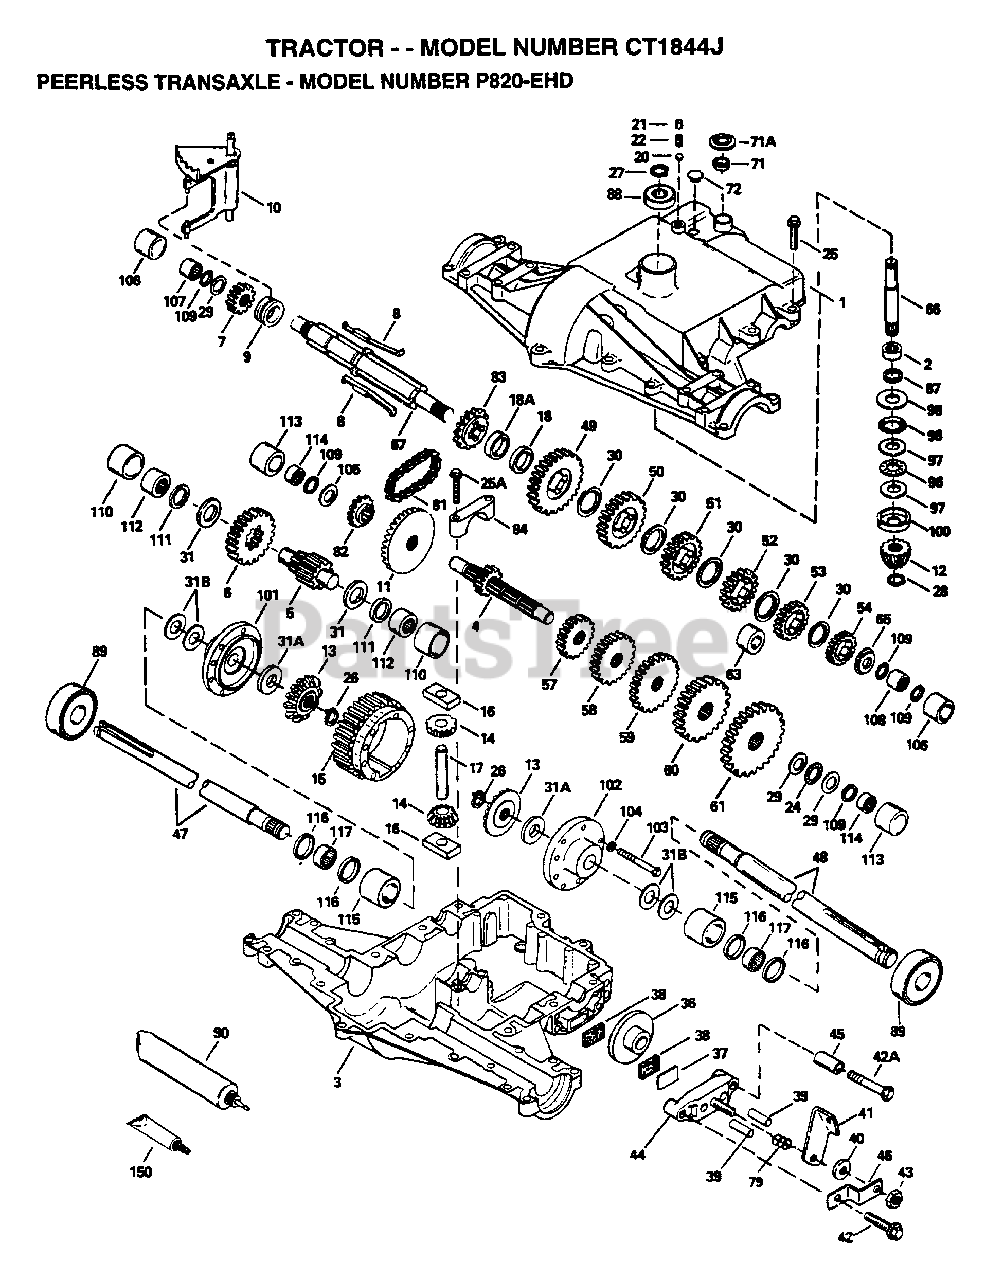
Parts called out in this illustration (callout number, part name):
1	COVER TRANSAXLE
2	BEARING NEEDLE
3	CASE TRANSAXLE
4	SHAFT COUNTER
5	SHAFT, OUTPUT, 9T
6	GEAR, OUTPUT, 35T
7	GEAR, SPUR, 15T
9	COLLAR SHIFT
10	ROD AND FORK ASSY SHIFT
11	GEAR BEVEL, 33T
12	BEVEL PINION, 13T
14	PINION, 10T
15	GEAR, RING, 31T
16	BLOCK DRIVE
18	SPACER, .350/.340 THICK
18A	SPACER, .276/.268 THICK
20	BALL STEEL, 5/16" DIA.
21	SCREW, 3/8-16 X 3/8"
24	THRUST BEARING
25	SCREW HEX HD 5/16-18 X 1-1/4
25A	SCREW, 1/4-20 X 1-1/4
28	RETAINING RING
29	WASHER THRUST
30	WASHER THRUST
31	WASHER THRUST
31B	WASHER THRUST
37	PLATE BRAKE PAD
41	LEVER BRAKE
42	SCREW, 1/4-20 X 1-1/4
42A	SCREW, 1/4-20 X 2-1/4
43	LOCKNUT 5/16-24
44	HOLDER BRAKE PAD
46	BRKT BRAKE LEVER
47	AXLE, 12-5/16" LONG
48	AXLE, 16-3/16" LONG
49	GEAR, SPUR, 41T
50	GEAR, SPUR, 35T
51	GEAR, SPUR, 30T
52	GEAR, SPUR, 25T
53	GEAR, SPUR, 22T
54	GEAR, SPUR, 19T
57	GEAR, SPUR, 15T
58	GEAR, SPUR, 20T
59	GEAR, SPUR, 25T
60	GEAR, SPUR, 28T
61	GEAR, SPUR, 31T
66	SHAFT INPUT
67	SHAFT BRAKE
71	SEAL SQUARE CUT
72	PLUG, THRDED, 9/16-18
81	CHAIN, ROLLER
82	SPROCKET 9T
83	SPROCKET 18T (REV)
84	BEARING CAP
87	OIL SEAL 3/4
88	BEARING BALL
89	BEARING BALL
90	GREASE BENTONITE, 32 OZ.
96	BEARING THRUST
97	WASHER THRUST
100	WASHER CUPPED
101	CARRIER DIFF THREADED HOLES
102	CARRIER DIFF
103	SCREW, 1/4-20 X 2-1/4
104	WASHER LOCK 1/4
107	BEARING NEEDLE
108	BEARING NEEDLE
110	SLEEVE STEPPED
111	RING SQ CUT
112	BEARING NEEDLE CAPPED
113	SLEEVE STEPPED
114	BEARING NEEDLE CAPPED
115	SLEEVE STEPPED
116	RING SQ CUT
117	BEARING NEEDLE
150	GASKET ELIMINATOR
